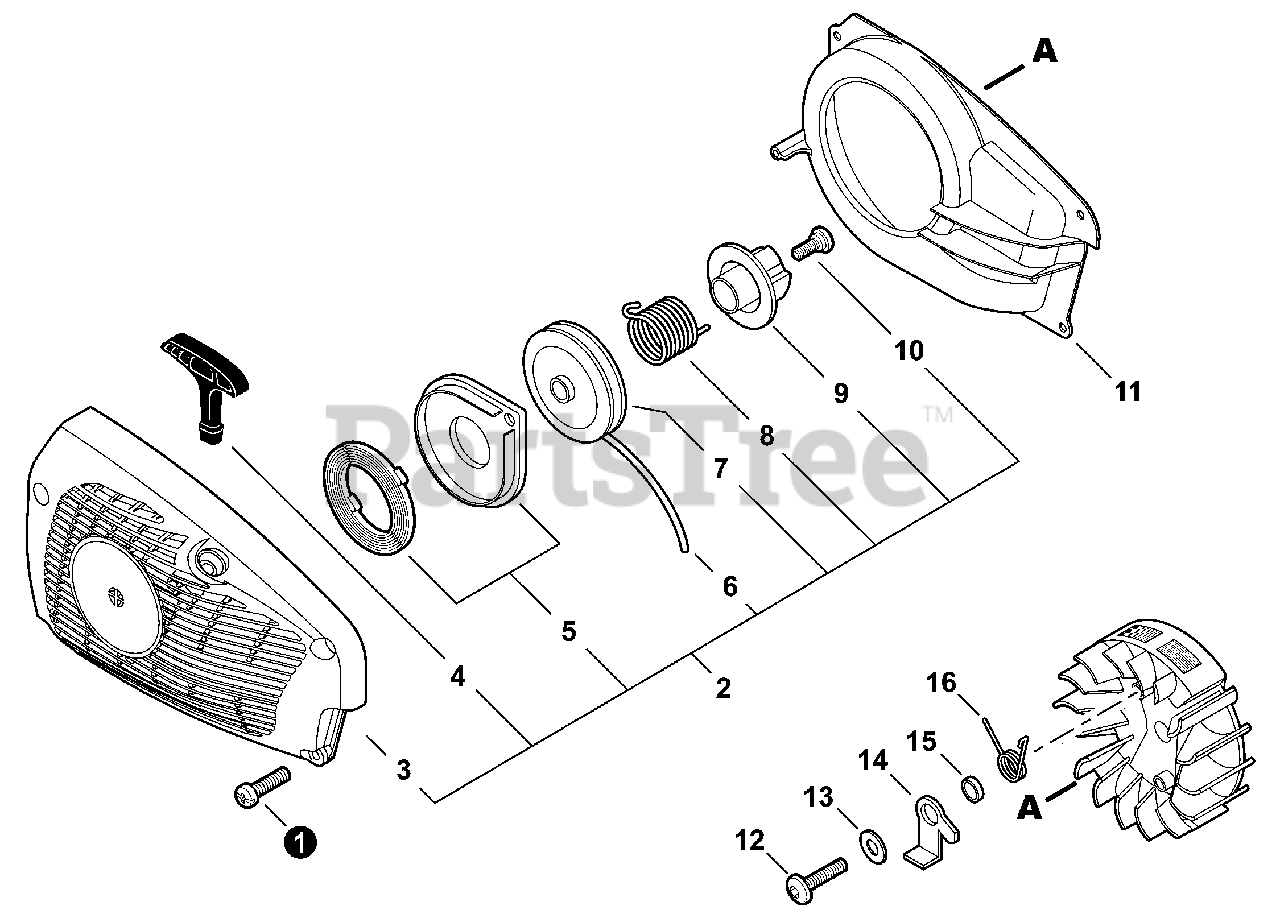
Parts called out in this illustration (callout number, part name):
1	BOLT, TORX 4×16
2	STARTER ASSY, RECOIL
3	CASE, STARTER
4	GRIP, STARTER
5	SPRING KIT, RECOIL
6	ROPE, STARTER 3.5×900
7	REEL, ROPE
8	SPRING, RETURN
9	PLATE, CAM
10	SCREW
11	COVER, FAN
12	BOLT 5×14
13	WASHER 5.5×12×0.8
14	PAWL, STARTER
15	SPACER 5.2×8×2.1
16	SPRING, TORSION
